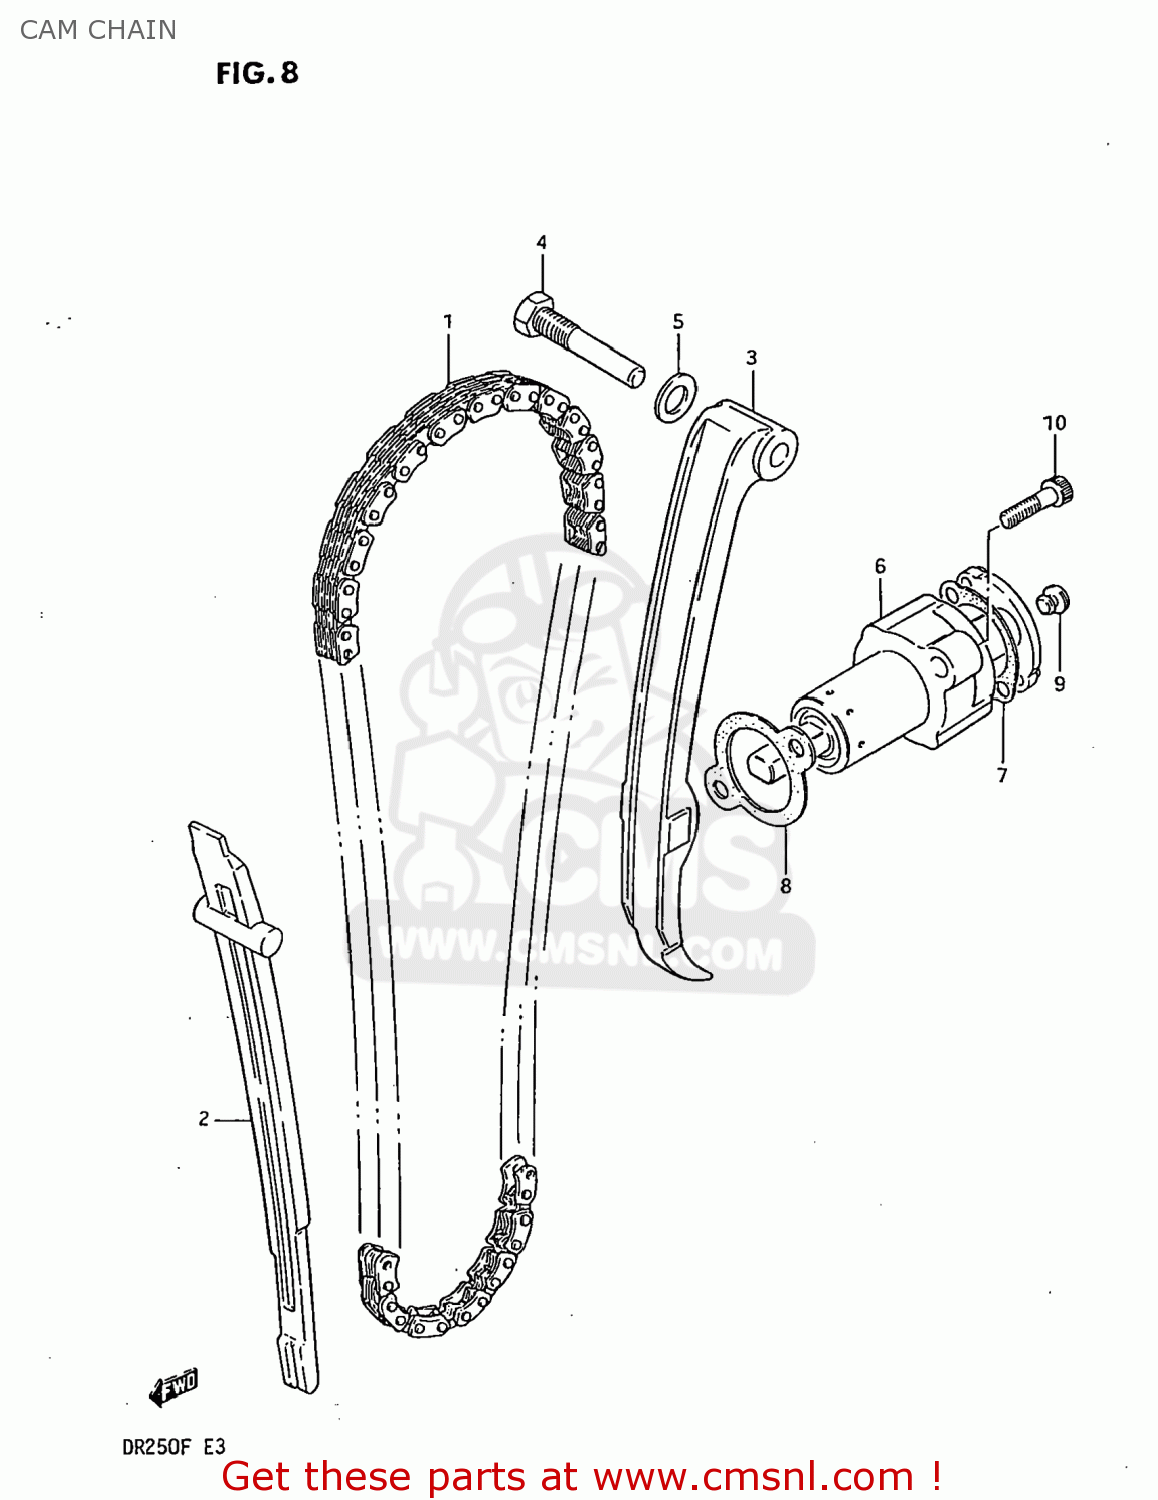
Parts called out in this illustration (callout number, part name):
1	CHAIN,CAMSHAFT DRIVE
2	GUIDE,CAM CHAIN
3	TENSIONER,CAM CHAIN
4	BOLT,CAM CHAIN TENSIONER
5	GASKET 8.2X14X1 (NAS)
6	ADJUSTER ASSEMBLY,TENSIONER
7	GASKET,ADJUSTER CAP (MCA)
8	GASKET,TENSIONER ADJUSTER (MCA)
9	PLUG,ADJUSTER
10	BOLT
